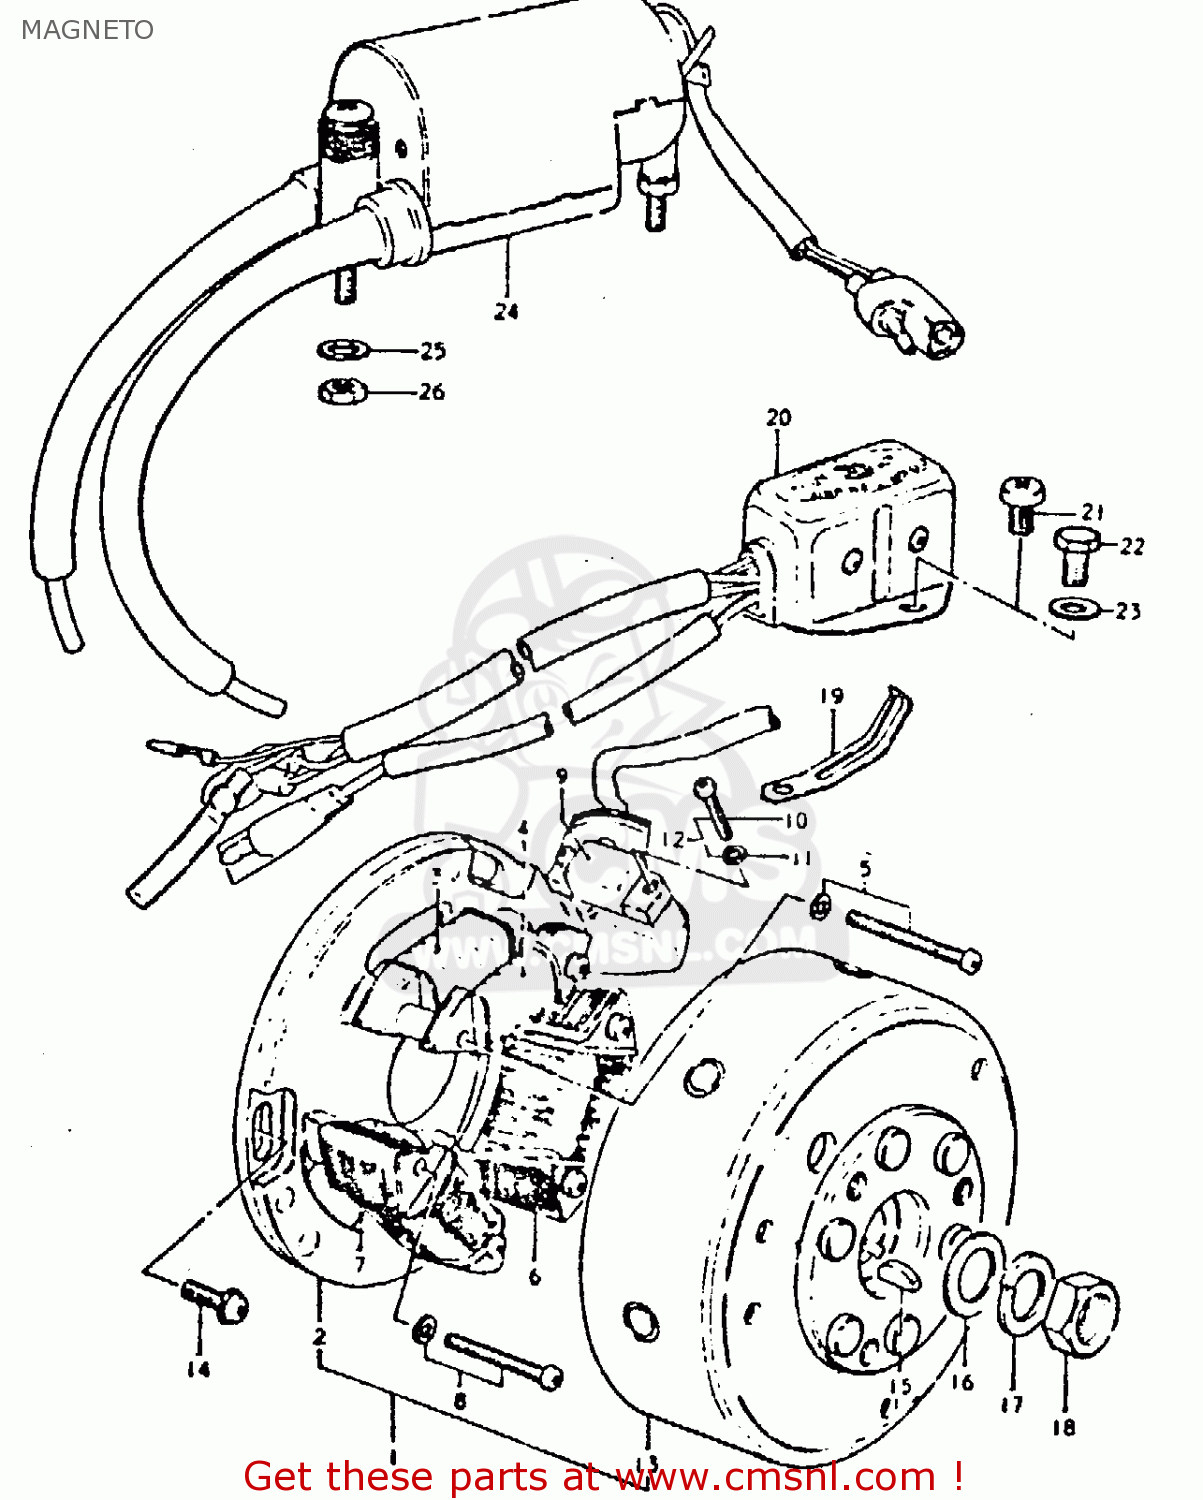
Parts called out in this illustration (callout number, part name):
1	MAGNETO ASSY
2	STARTER ASSY
3	COIL ASSY,PRIMARY NO.2
4	COIL ASSY,PRIMARY NO.1
5	SCREW
6	COIL
7	COIL ASSY,CHARGING NO.1
8	SCREW
9	COIL, PUISER
10	SCREW 4X25
11	LOCK WASHER
12	SCREW
13	ROTOR
14	SCREW(5X14)
15	KEY
16	WASHER
17	WASHER,LOCK 12
18	NUT
19	CLAMP L:35
20	CDI UNIT
21	SCREW
22	BOLT, UPPER
23	WASHER (6.5X17X1.6)
24	COIL ASSY,IGNITION
25	WASHER
26	NUT
